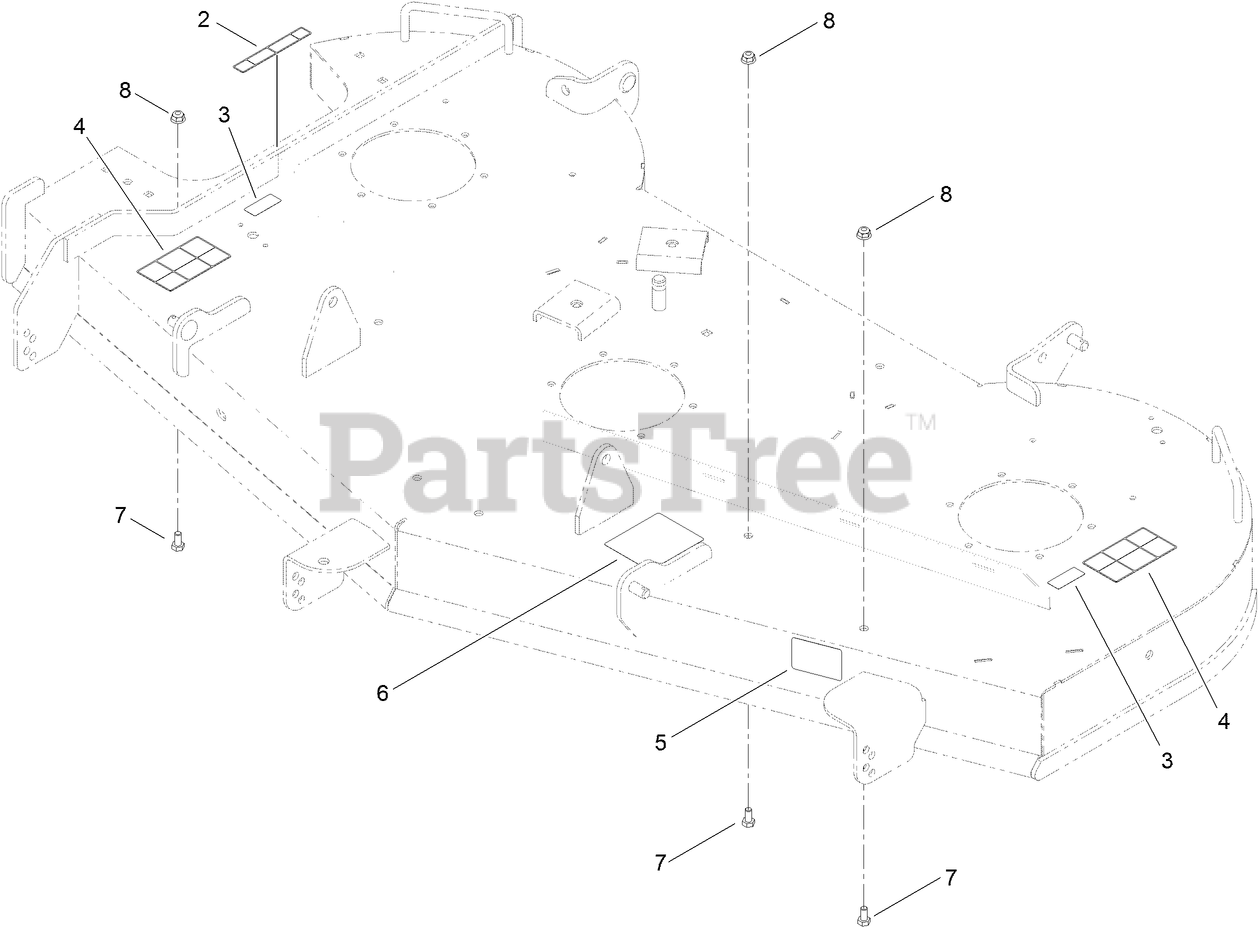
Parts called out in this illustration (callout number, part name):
2	DECAL-DANGER
3	DECAL-DANGER
4	DECAL-DANGER
5	DECAL-SCALP, ANTI
6	DECAL-ROUTING, BELT
7	SCREW-HH
8	NUT-HF, NI
